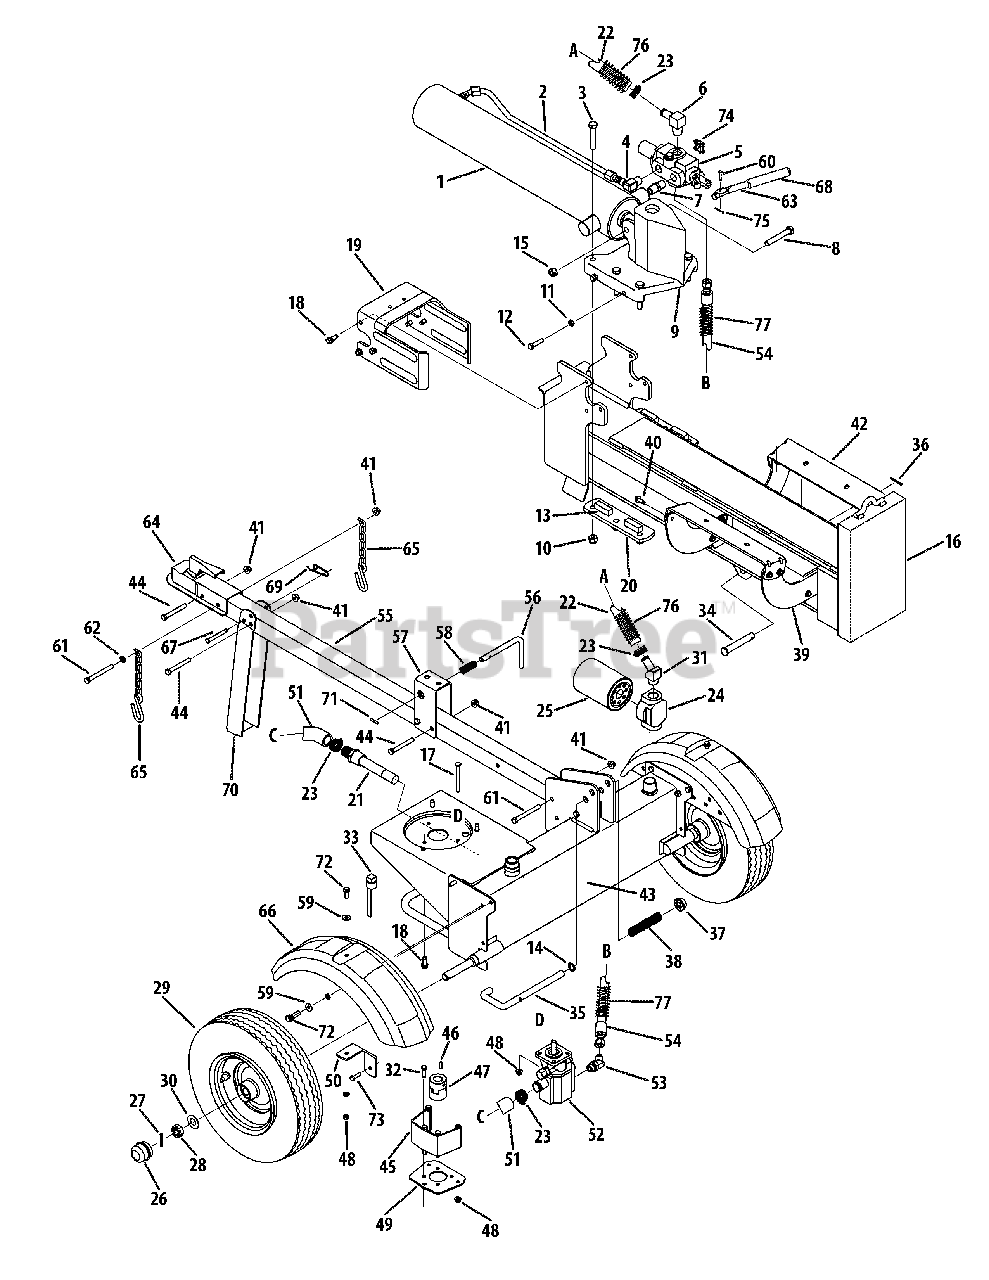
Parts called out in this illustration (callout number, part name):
1	Hydraulic Cylinder
1	Kit Seal 4.5" for XINGHUI cylinder 718-0769A
1	Kit Seal 4.5" for ENERGY cylinder 718-0769A
2	Hydraulic Tube
3	Hex Cap Screw, 1/2-20 x 2.75
4	90 Degree Solid Adapter
5	Control Valve
6	Return Elbow
7	Nipple Pipe, 1/2-14
8	Hex Cap Screw, 1/2-13 x 3.25
9	Wedge Assembly
10	Hex Lock Nut, 1/2-20
11	Hex Jam Nut, 3/8 -24
12	Hex Cap Screw, 3/8 -24 x 1.5
14	Flat Washer, .635 x.93 x.06
15	Hex Lock Nut,1/2-13
16	Beam Assembly
17	Hex Screw, 5/16-18 x 3.25
18	Hex Washer Screw, 3/8-16 x 1.0
20	Back Plate
21	Inlet Filter
22	Return Hose, 3/4" ID x 44" Lg.
23	Hose Clamp, 5/8 "
24	Filter Housing
25	Oil Filter
26	Hub Cap
27	Cotter Pin
28	Slotted Nut, 3/4-16
29	Wheel Assembly
30	Flat Washer, .760 ID x.500 OD
31	Adapter, 3/4-14
32	Hex Screw, 5/16-18 x 1.00
33	Vented Dipstick
34	Clevis Pin
35	Lock Rod
36	Cotter Pin
37	Push Cap
38	Compression Spring
39	Log Tray Bracket
40	Hex Washer Hd. Screw, 5/16-18 x .750
41	Flange Lock Nut, 3/8 -16
43	Frame Assembly
44	Hex Bolt, 3/8-16 x 3"
45	Coupling Shield
46	Square Key, 3/16" x.75
47	Flexible Coupling .875 X .500
47	Spider Bushing
47	Flexible Coupling .500
47	Flexible Coupling .875
48	Flange Lock Nut, 5/16-18
49	Rear Coupling Support Bracket
50	Fender Mounting Bracket
52	Gear Pump .500
53	45 Degree Elbow Fitting
54	High Pressure Hydraulic Hose
55	Tongue Assembly
56	Latch Rod
57	Latch
58	Compression Spring
59	Flat Washer
60	Clevis Pin
61	Hex Cap Screw, 3/8-16 x 3.50
62	Flat Washer, .375 x.738 x.063
63	Hydraulic Valve Control
64	Hitch Coupling Assembly
66	Fender
67	Clevis Pin
69	Spring Pin
72	TT Screw, 5/16-18 x 0.875"
73	TT Screw, 5/16-18 x 1.00
74	Valve Handle Link
75	Cotter Pin
76	Hose Guard, 44" - 570 Series
77	Hose Guard, 48" - 570 Series
